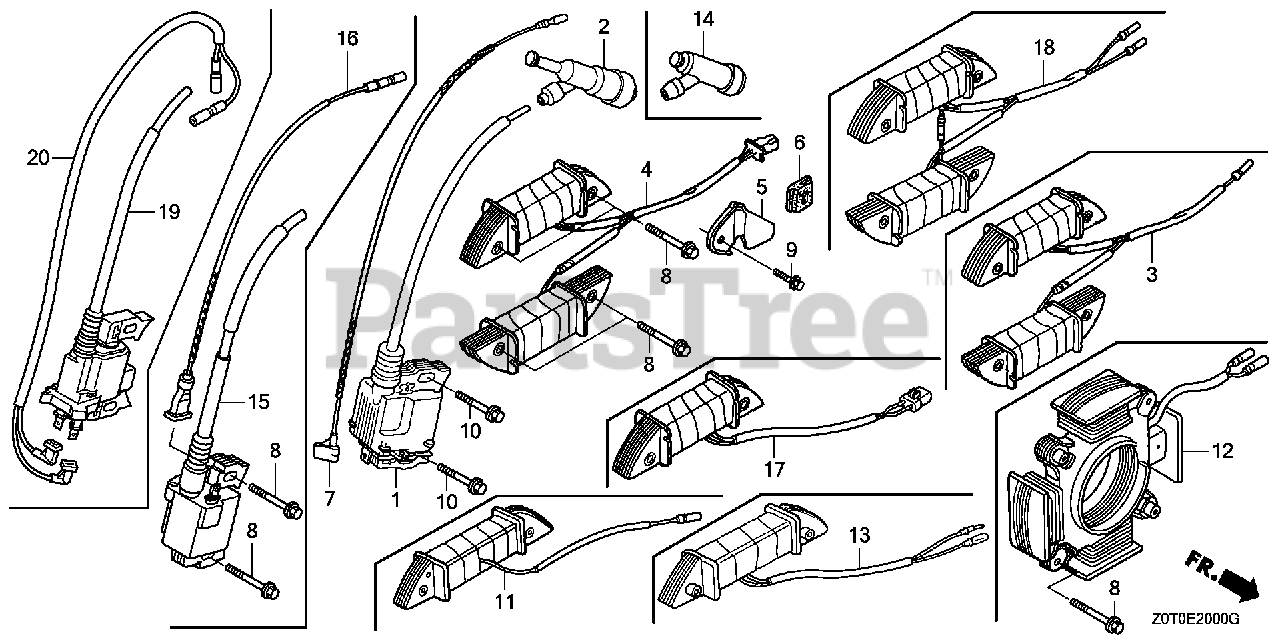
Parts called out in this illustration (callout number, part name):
2	CAP ASSY., NOISE SUPPRESSOR (TEC)
10	BOLT, FLANGE (6X25) Use up to Engine SN 2056819.
19	COIL ASSY., IGNITION
20	WIRE, STOP SWITCH
